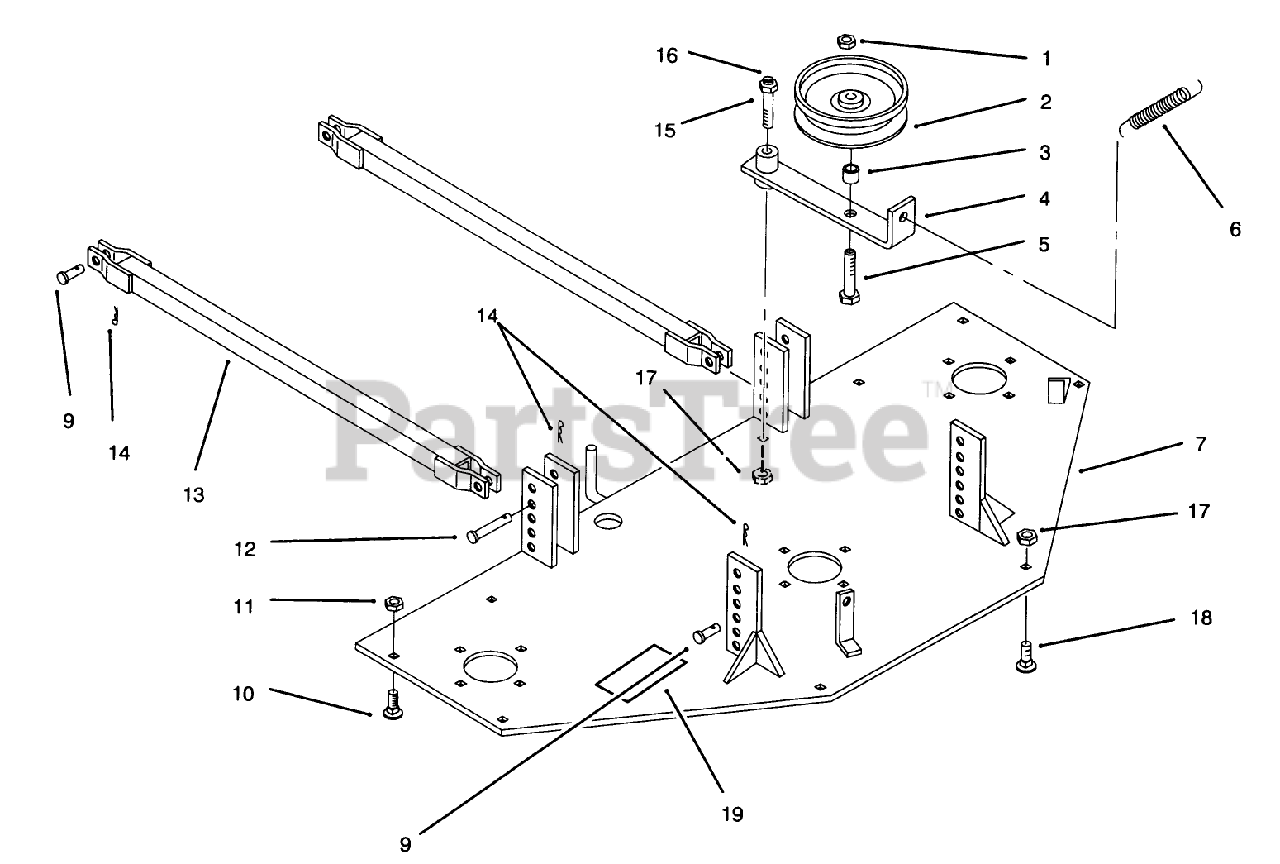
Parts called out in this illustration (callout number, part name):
1	NUT-LOCK, NI
2	PULLEY FLAT B
3	SPACER
4	ASS'Y-IDLER ARM R
5	SCREW-HH
6	SPRING-EXTENSION
7	ASS'Y-MWR DECK PL R
9	CLEVIS PIN3/8X1 1/4
10	BOLT-CARR
11	NUT-LOCK, NI
12	CLEVIS PIN
13	Bar-Stabilizer
14	HAIRPIN
15	Bolt-Shoulder (Incl. Ref. #16)
16	FITTING-GREASE, 90 DEG
17	NUT-LOCK, NI
18	BOLT-CARR
19	DECAL-BELT INSTAL
